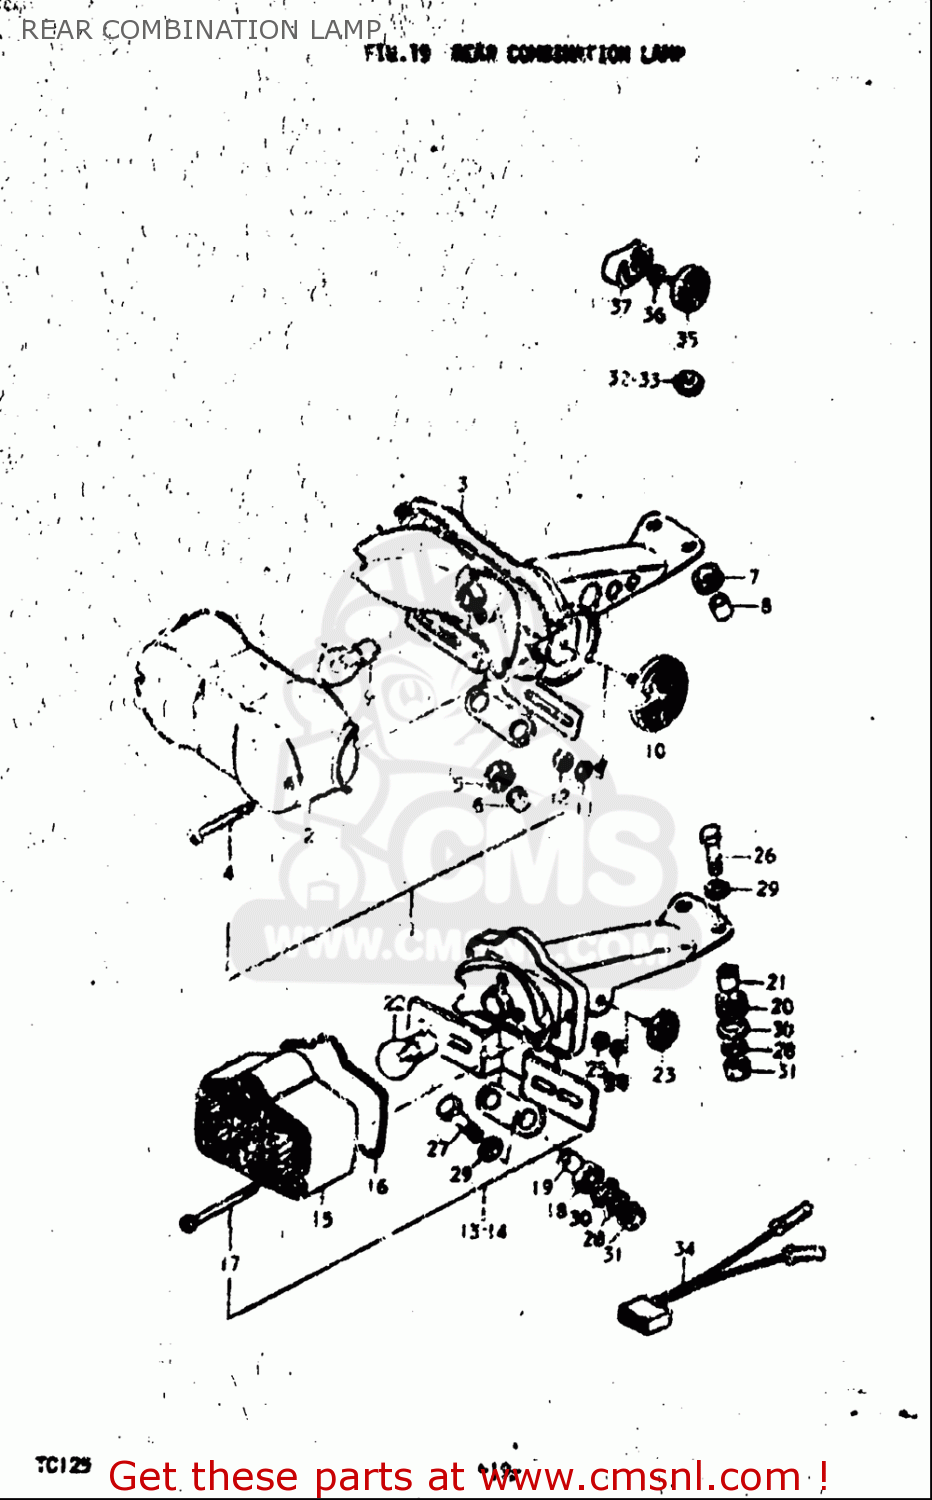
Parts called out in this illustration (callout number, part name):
2	LENS,RR COMBINATION LAMP
4	SCREW
5	CUSHION
6	SPACER
7	CUSHION
9	BULB(6V17/5.3W,STANLEY,A4813)
11	WASHER,LOCK
12	NUT
15	LENS
16	GASKET (NAS)
18	CUSHION
19	SPACER
20	CUSHION
21	SPACER
22	BULB(6V32/3CP,STANLEY)
24	WASHER,LOCK
25	NUT
26	BOLT
27	BOLT
28	WASHER,LOCK
29	WASHER
30	WASHER(6.5X20X1.6)
31	NUT
35	REFLEX REFLECTOR,RR
36	SPACER(6.5X9X6.7)
37	SPACER
